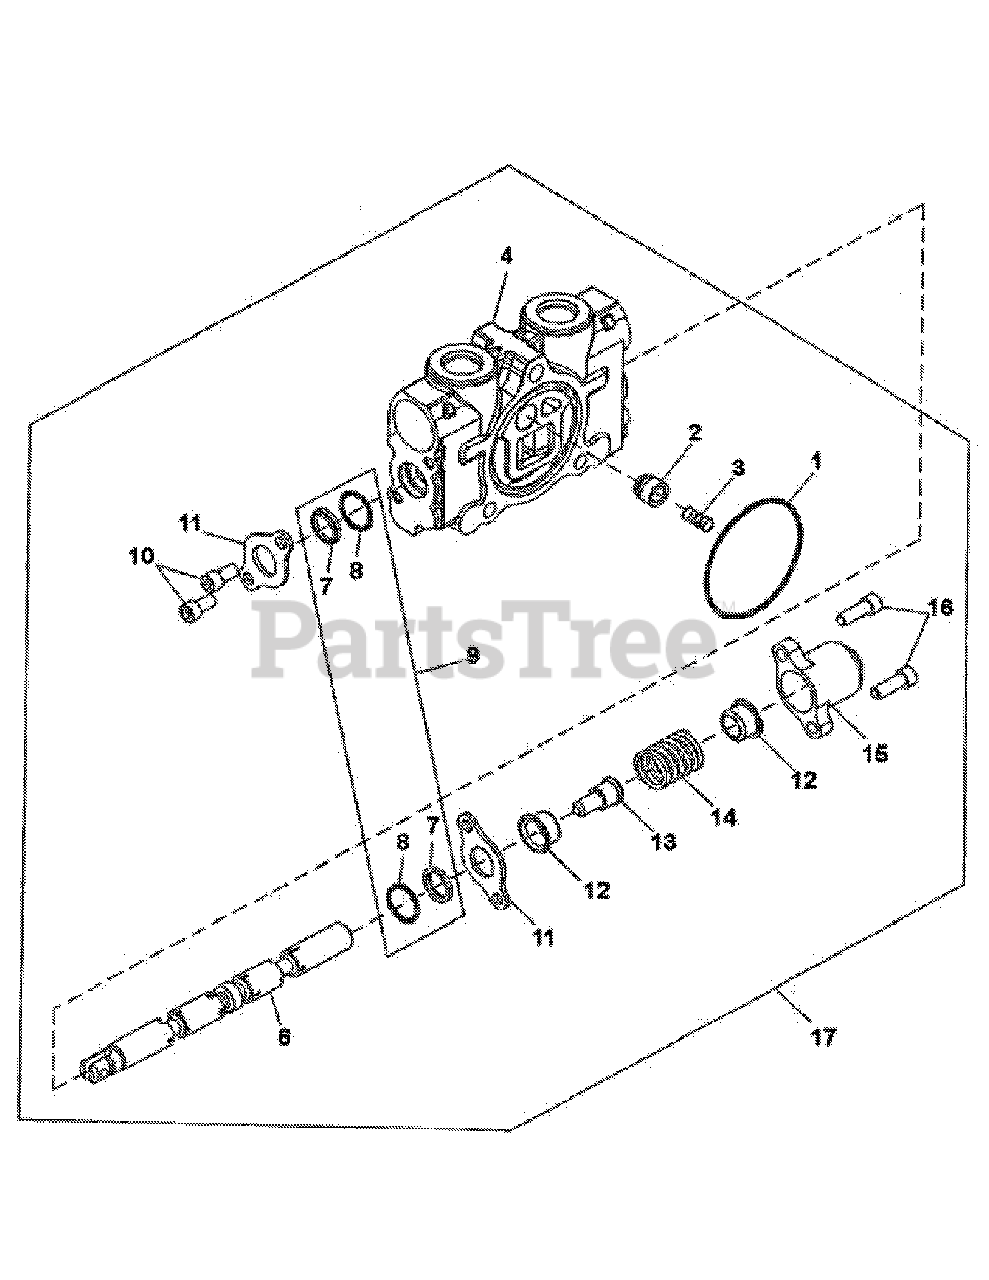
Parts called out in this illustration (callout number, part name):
1	O-Ring
2	Poppet, Load Check
3	Spring, Load Check
4	Valve Section
6	Spool
7	Wiper, Spool
8	O-Ring, Spool
9	Seal Kit, Minor (contains two of Item 7 & 8)
10	Cap Screws, Socket Head
11	Plate, Retainer
12	Seat, Spring
13	Screw, Spring Seat
14	Spring, Spool Centering
15	Cap, Spring Spool
16	Cap Screws, Socket Head
17	Valve Section Assembly
18	Seal Kit, Major
19	Load Check Poppet Kit
20	Spring Centered Spool Positioner Kit
21	Restrictor Assembly - .073" Diameter
